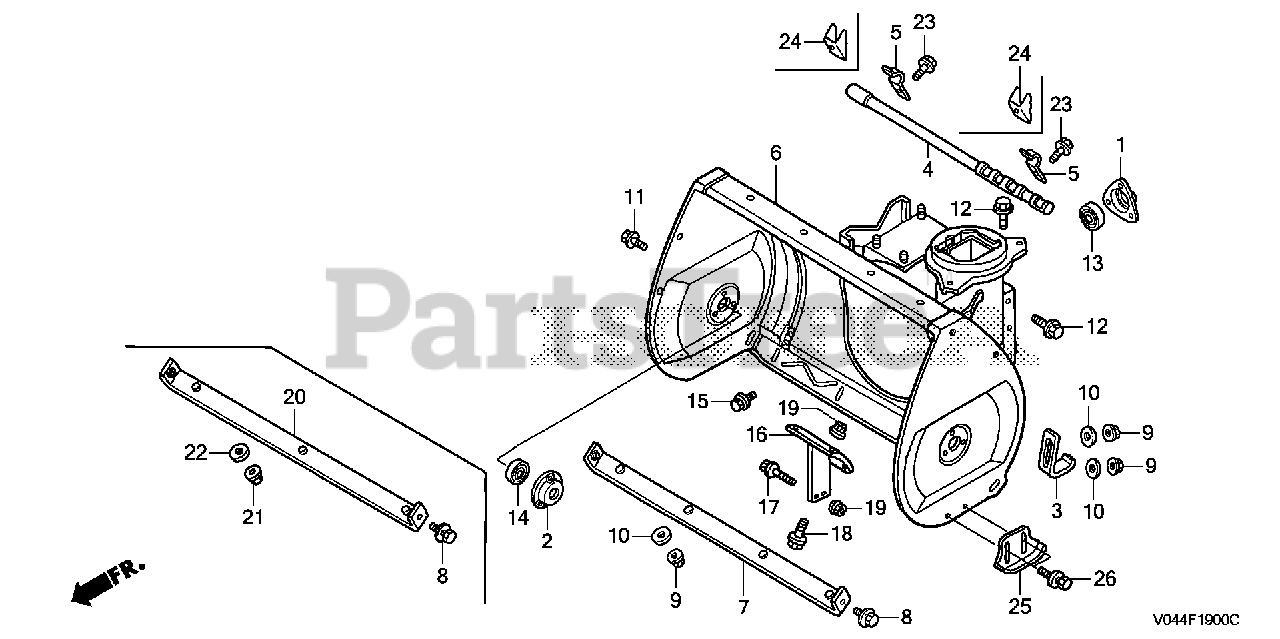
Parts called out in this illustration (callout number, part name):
1	HOLDER, WHEEL SHAFT BEARING
2	HOLDER, AUGER BEARING
3	SKID, AUGER
4	BAR, HEIGHT ADJUSTMENT
5	BRACKET, HEIGHT ADJUSTMENT BAR
5	BRACKET, SNOW DROP BAR
6	HOUSING, AUGER *R280* (POWER RED)
7	GUARD, AUGER HOUSING
8	BOLT-WASHER (6X16)
9	NUT, FLANGE (6MM)
10	WASHER, PLAIN (6MM)
11	BOLT, FLANGE (6X10)
11	BOLT, FLANGE (6X12) Use up to Engine SN 1543277.
12	BOLT, FLANGE (8X16) Use from Engine SN 1000016.
13	BEARING, RADIAL BALL (6004UU)
14	BEARING, RADIAL BALL (6203UU)
15	BOLT, FLANGE (6X12)
16	BRKT,AUGER HSG
16	BRACKET, AUGER HOUSING
17	BOLT, FLANGE (8X25)
18	BOLT, FLANGE (8X14)
19	NUT, FLANGE (8MM)
23	BOLT, FLANGE (6X8)
23	BOLT, FLANGE (6X12) Use up to Engine SN 1543277.
24	PLATE, SNOW DROP BAR
